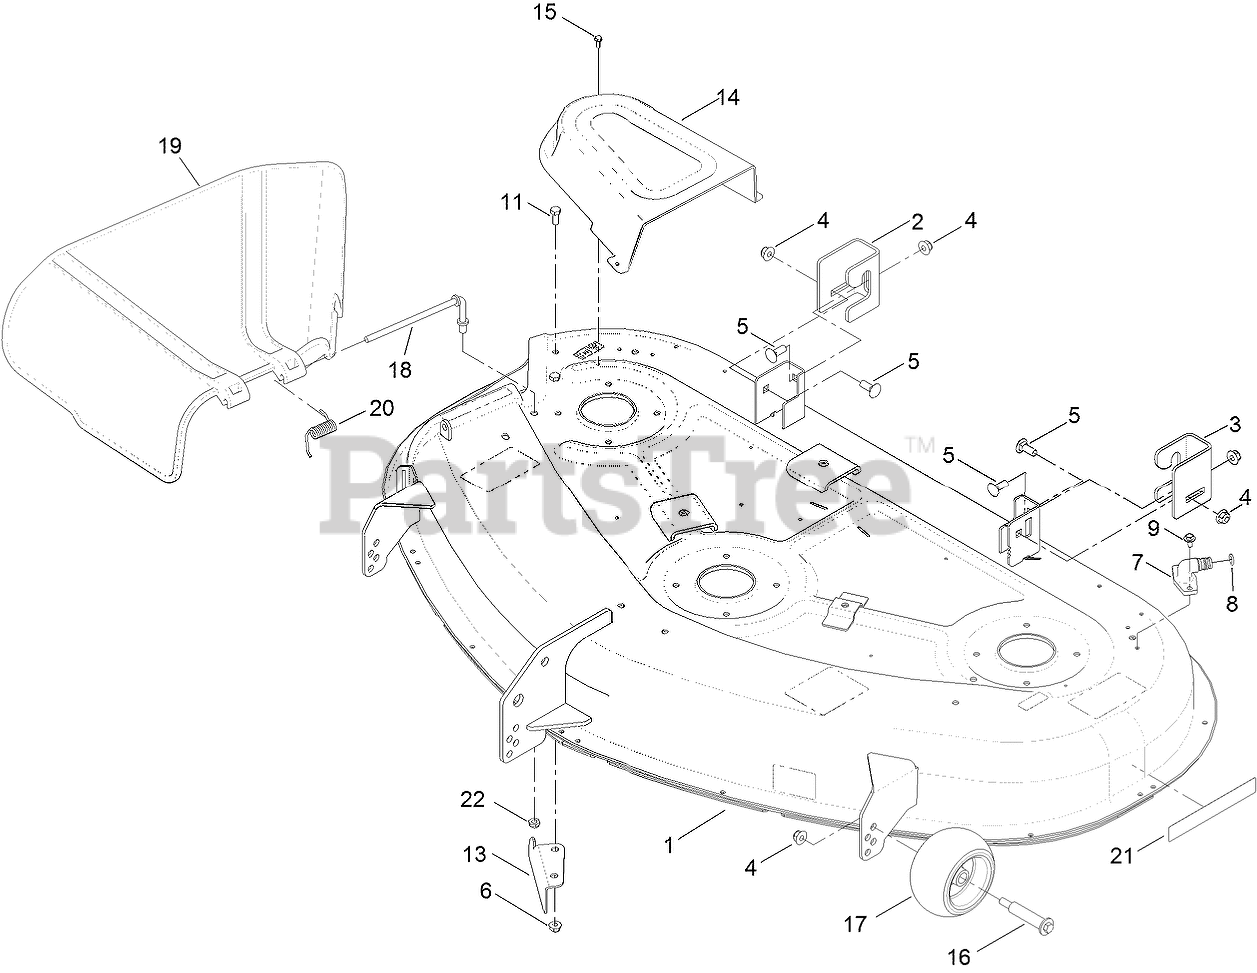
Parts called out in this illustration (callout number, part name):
1	50 INCH DECK AND DECAL ASM
2	BRACKET-HANGER, RH
3	BRACKET-HANGER, LH
4	NUT-HF, NI
5	BOLT-CARR
6	NUT-HF, NI
7	FITTING-WASHOUT
8	O-RING
9	SCREW-HHFTF
11	SCREW-HH
13	BAFFLE-CUTOFF
14	COVER-BELT
15	SCREW-TAPTITE
16	BOLT-SHOULDER
17	ROLLER-SCALP, ANTI
18	ROD-PIVOT
19	DEFLECTOR
20	SPRING-TORSION
21	DECAL-RECYCLER
22	NUT-LOCK, NI
